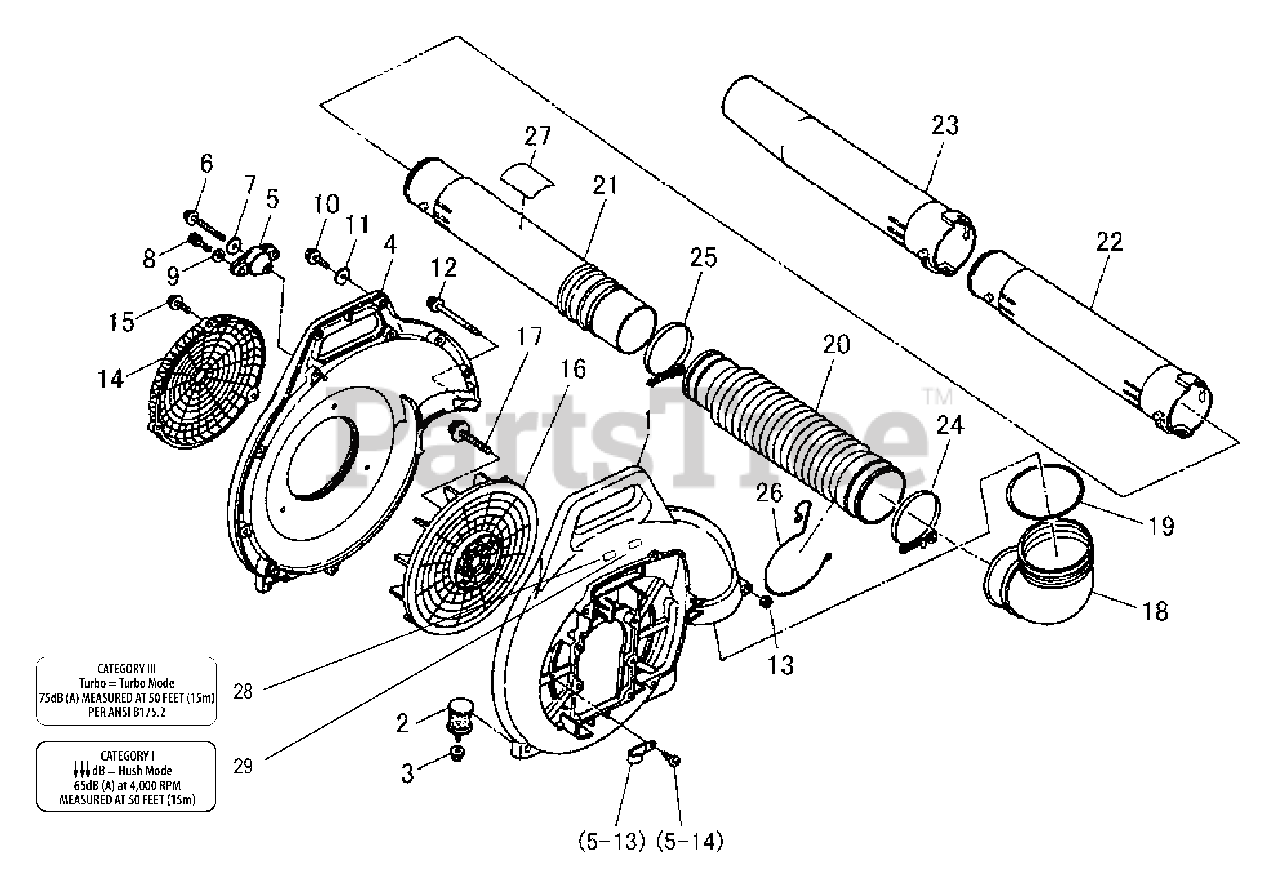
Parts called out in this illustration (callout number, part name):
1	CASE, VOLUTE
2	CUSHION, AV 6
3	NUT, FLANGE M6
4	COVER, FAN
5	CUSHION, AV 5
6	BOLT TAPPING M5
7	WASHER Ø25ר5.5×2
8	BOLT M5×16
9	WASHER Ø15ר5.2×1.6
10	BOLT M5×20
11	WASHER, FLAT 5.5×10×0.8
12	BOLT M5×70
13	NUT M5
14	COVER, INTAKE
15	BOLT, TAPPING
16	FAN
17	BOLT M6×40
18	TUBE, BLOWER - ELBOW
19	O-RING
20	TUBE, FLEXIBLE
21	TUBE, BLOWER - SWIVEL
22	TUBE, BLOWER - STRAIGHT
23	NOZZLE
24	CLAMP Ø100
25	CLAMP Ø85
26	HOLDER, THROTTLE CABLE
27	LABEL, MODEL
28	LABEL, NOISE
29	LABEL, NOISE
